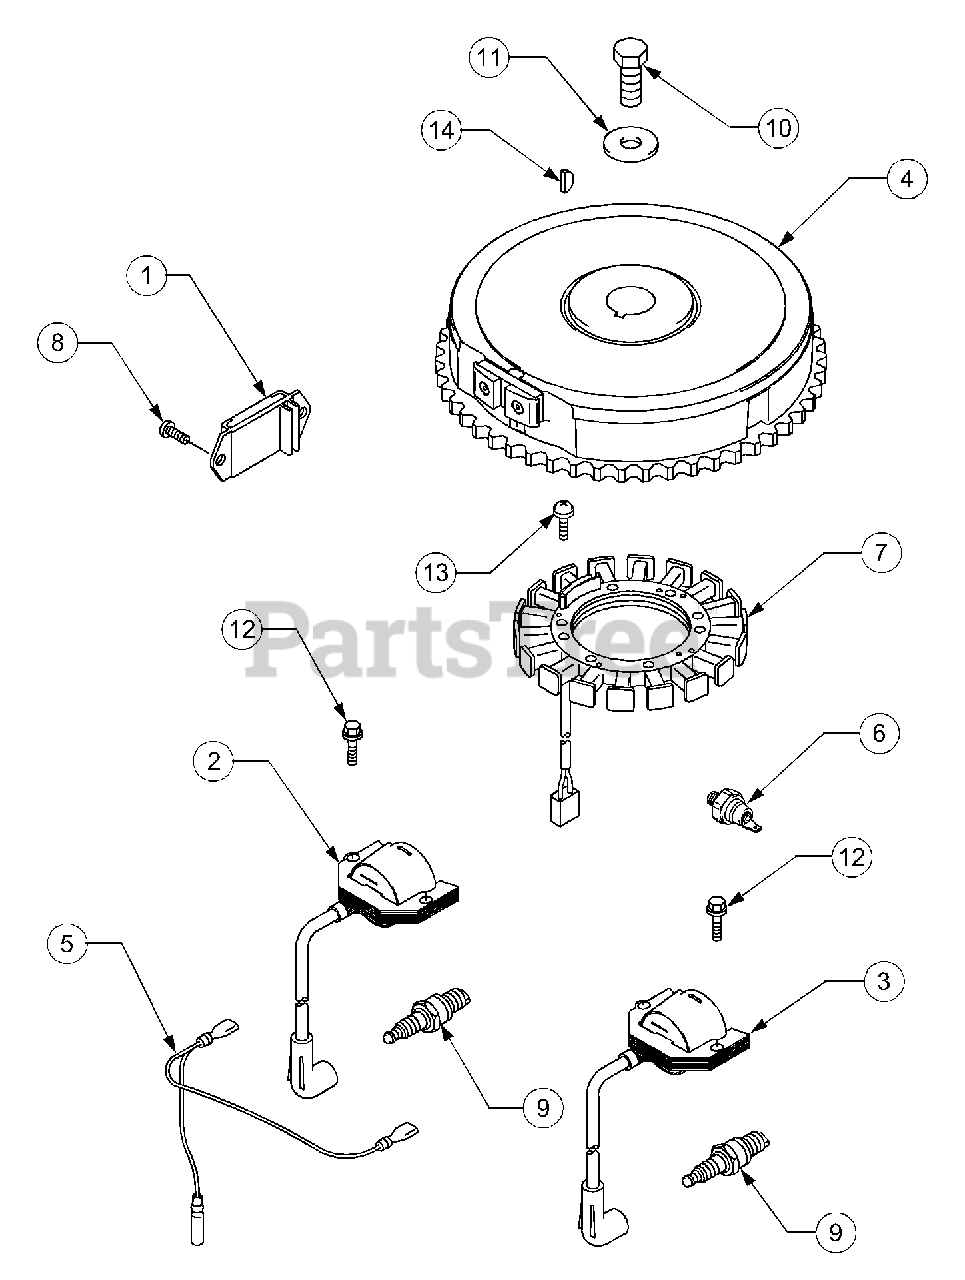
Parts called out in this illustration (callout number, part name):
1	Regulator, Voltage
2	Coil Assy, Ignition
3	Coil Assy, Ignition
4	Flywheel Assy
6	Switch, Oil Pressure
7	Coil, Charging
9	Plug, Spark - RCJ8Y
10	Bolt, 12x30
12	Bolt, Flanged
13	Screw, Pan Hd. Cross
14	Key, Woodruff
